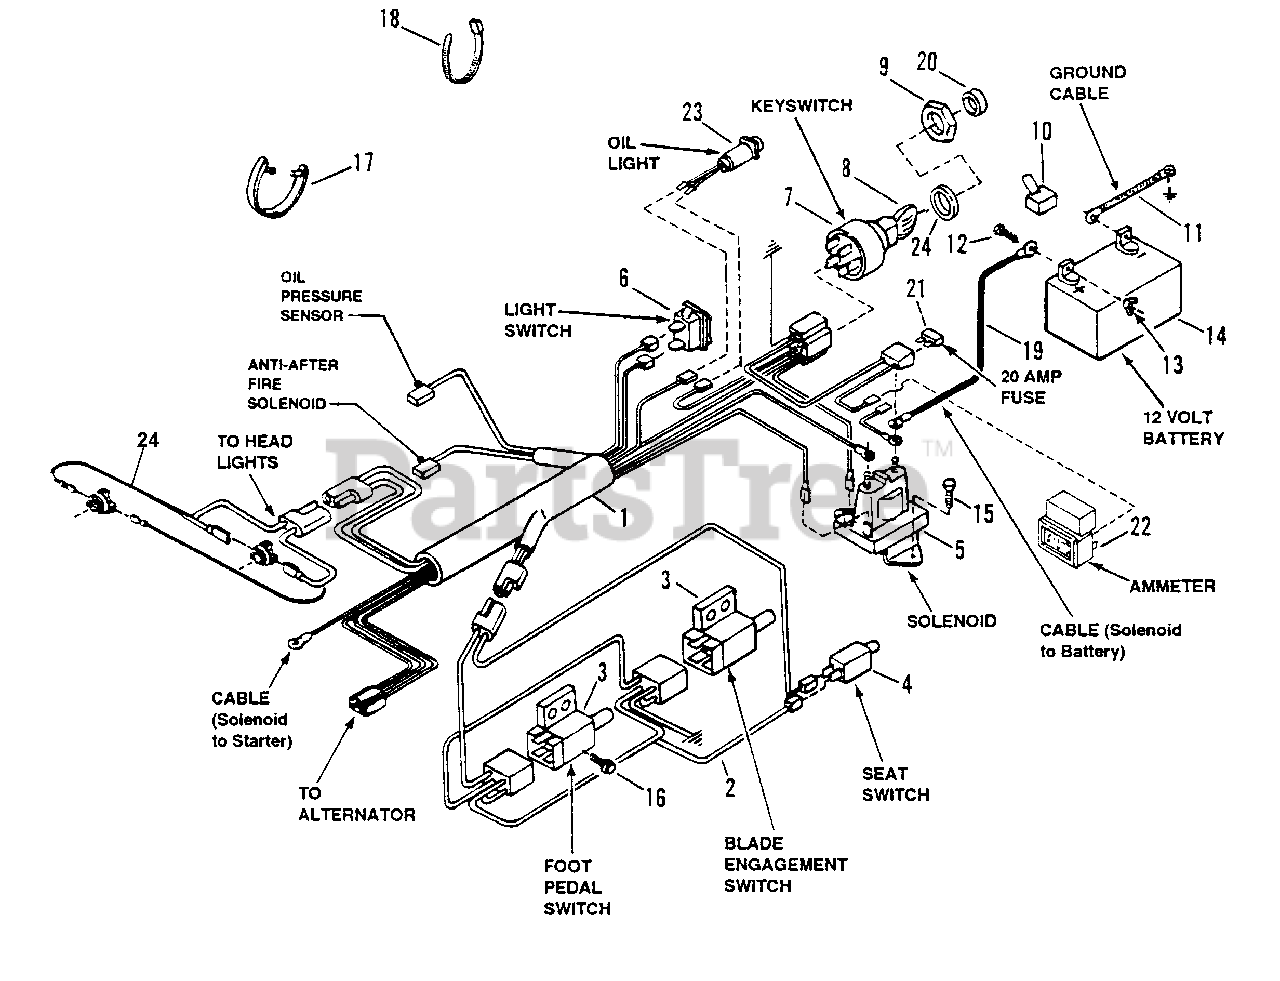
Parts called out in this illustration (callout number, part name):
1	HARNESS, Wiring (Briggs Engine)
2	HARNESS, Interlock
3	SWITCH, Clutch & PTO (NC/NO)
4	SWITCH, Seat (NC)
5	SOLENOID
6	SWITCH, Light
7	SWITCH, Key
8	KEY, Switch (With Cover)
9	NUT, 5/8-32 Hex
10	COVER, Positive Terminal
11	CABLE, Negative 15" 8 AWG Black
12	BOLT, 1/4-20 x 3/4" Carriage
13	NUT, 1/4-20 Wing
14	KIT, Battery
15	SCREW, 1/4-20 x 1/2" Self-Tapping
16	SCREW, #10-24 x 1/2" Hex Washer Self-Tap (Torx)
17	TIE, Wire
18	TIE, Cable 7"
19	CABLE, Positive 11" 8 AWG Red
20	BEZEL
21	FUSE, 20 Amp
22	AMMETER
23	OIL LIGHT
24	HARNESS, Headlight M&G Sockets
